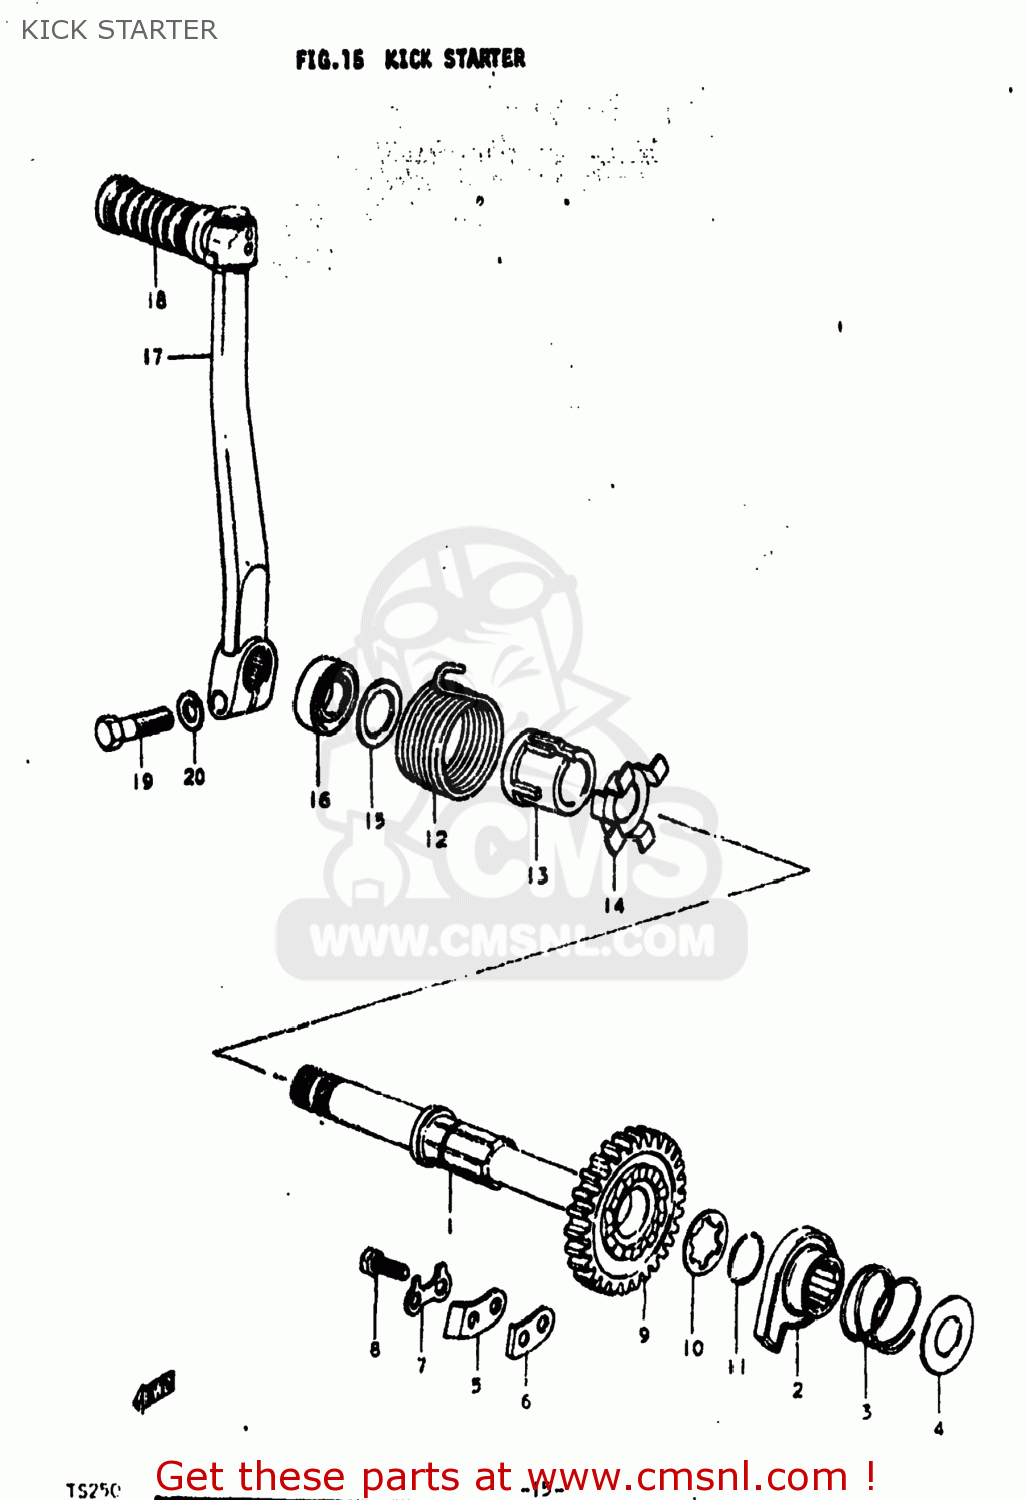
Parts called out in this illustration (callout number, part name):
1	SHAFT,KICK STARTER
2	STARTER,KICK
3	SPRING
4	WASHER
5	GUIDE,KICK STARTER
6	STOPPER,KICK STARTER
7	WASHER
8	BOLT
9	GEAR,KICK STARTER DRIVE
10	WASHER,LOCK
11	CIRCLIP
12	SPRING
13	GUIDE,KICK SHAFT SPRING
14	HOLDER,KICK SHAFT SPRING
15	WASHER
16	SEAL,OIL(20X37X7)
17	LEVER ASSEMBLY,KICK STARTER
18	RUBBER,KICK STARTER PEDAL
19	BOLT 10X30
20	LOCK WASHER
